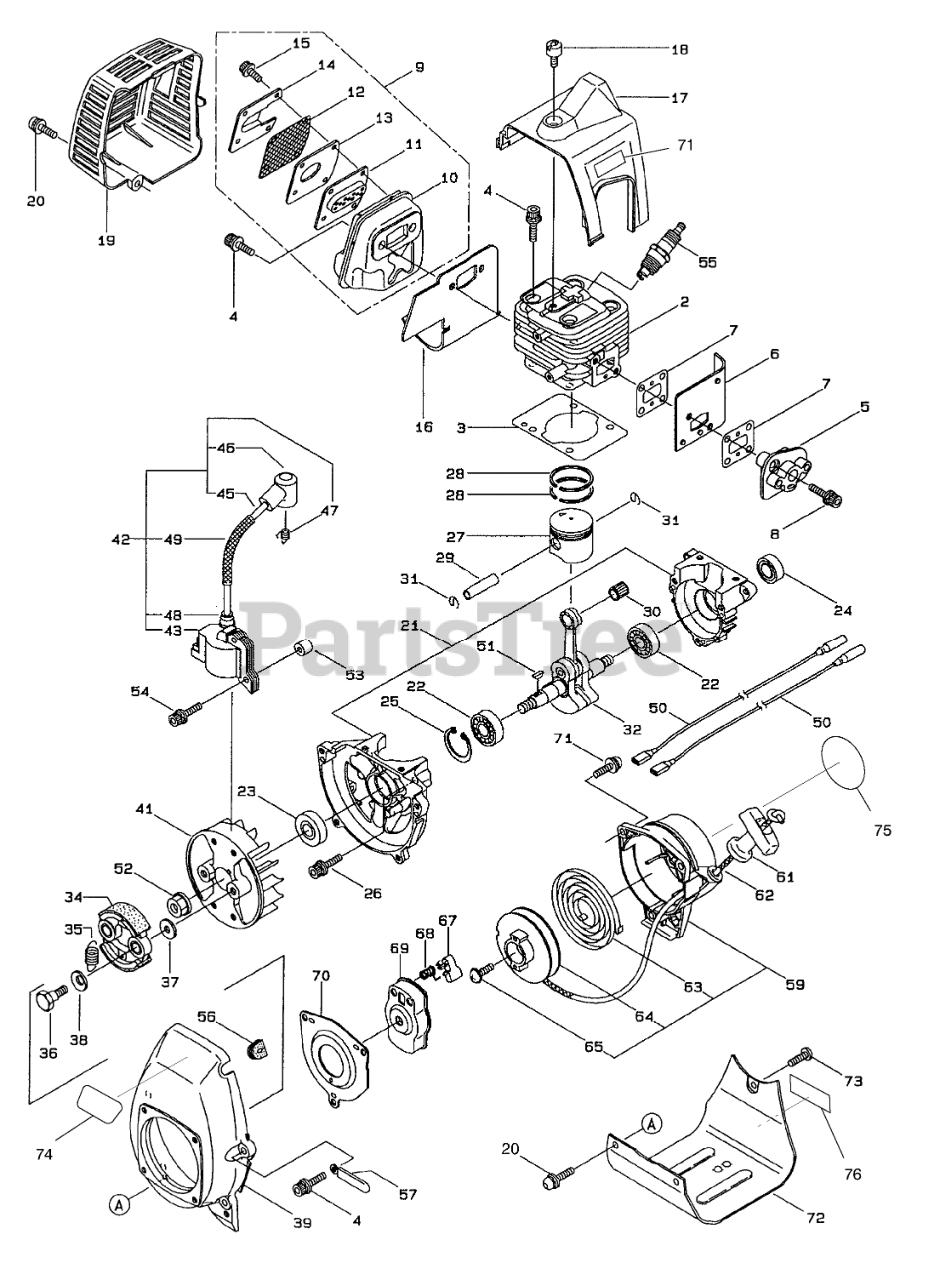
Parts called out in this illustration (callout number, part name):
2	CYLINDER
3	GASKET
5	INSULATOR
6	DUCT - AIR
7	GASKET
8	SCREW
9	Muffler Assembly (Incl. Ref. #10-15)
10	MUFFLER
11	PLATE
12	SCREEN
13	GASKET
14	OUTLET - EXHAUST
15	CAPSCREW
16	GASKET
17	COVER - CYLINDER
18	COVER - KNOB,TOP
19	COVER - MUFFLER
20	CAPSCREW
21	CRANKCASE
22	BEARING
23	SEAL - OIL
24	SEAL - OIL
25	RING - SNAP
27	PISTON
28	RING - PISTON
29	PIN - PISTON
30	BEARING - NEEDLE
31	CIRCLIP
32	CRANKSHAFT
34	SHOE - CLUTCH
35	SPRING - CLUTCH
36	BOLT - CLUTCH
37	WASHER
38	WASHER - WAVE
39	COVER - FAN
41	ROTOR
42	Ignition Coil Assembly (Incl. Ref. #43-49)
45	CABLE - IGNITION
46	CAP - PLUG
47	CONNECTOR
51	KEY - WOODRUFF
52	WASHER & NUT
53	SPACER
55	SPARK PLUG
56	GROMMET
57	CLAMP
59	Recoil Assembly (Incl. Ref. #60-65)
61	GRIP - STARTER
62	ROPE - STARTER
63	SPRING - SPIRAL
65	SCREW
68	SPRING - RETURN
69	STARTER
70	PLATE
71	DECAL - WARNING
72	STAND - ENGINE
73	SCREW
74	DECAL - TORO
75	DECAL - TORO
76	REPLACEMNT SERIAL PLT
